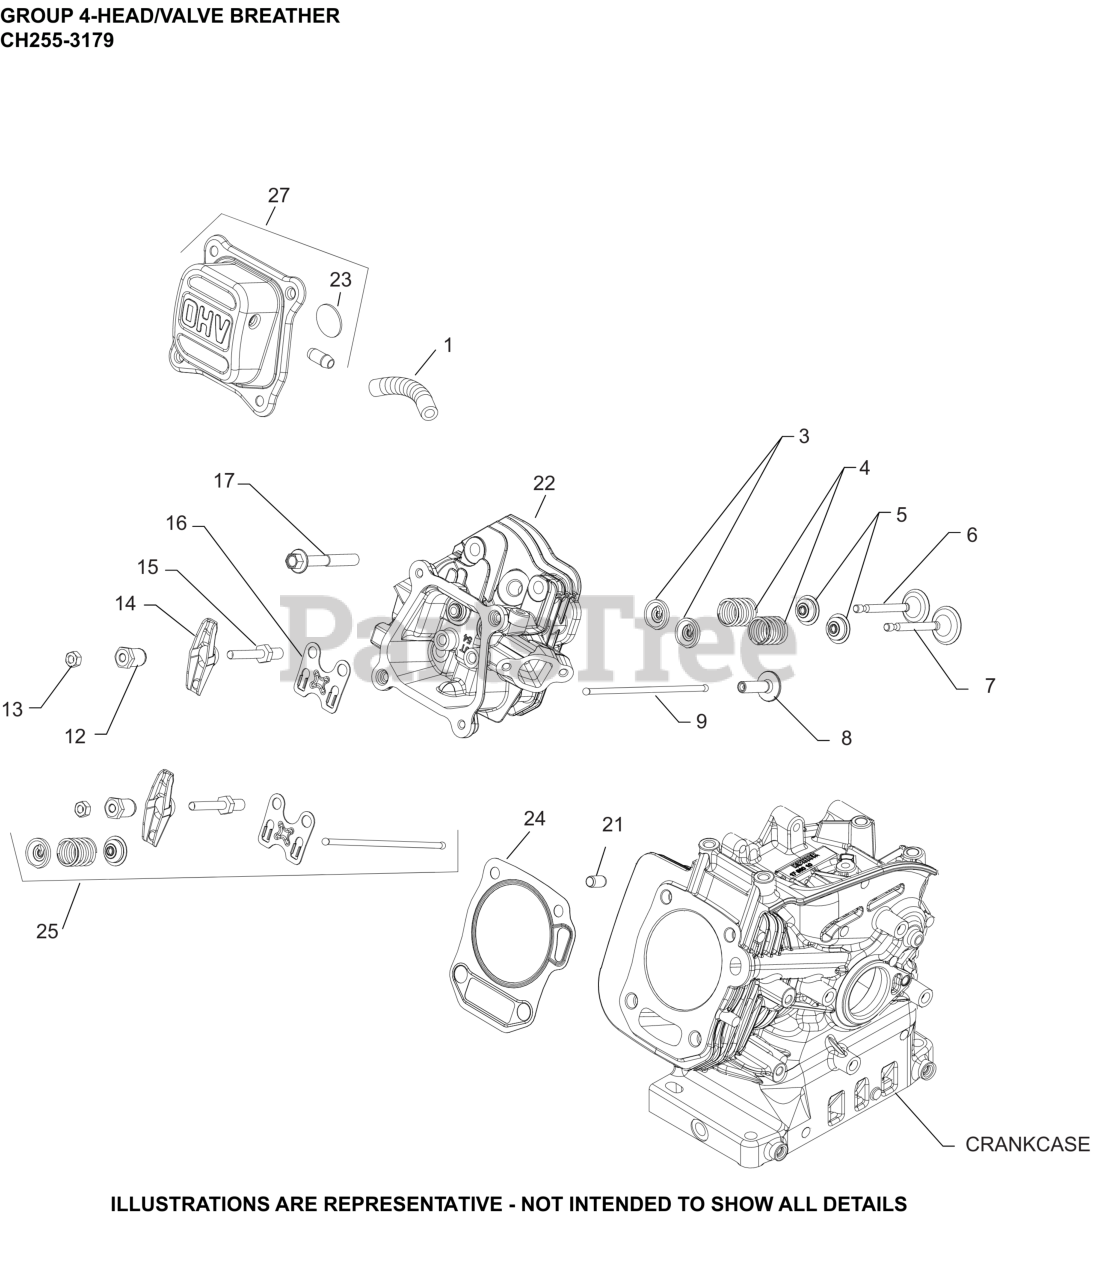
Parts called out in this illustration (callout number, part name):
1	TUBE, BREATHER
3	RETAINER, VALVE SPRING
4	SPRING, VALVE
5	SEAL, VALVE
6	VALVE, EXHAUST
7	VALVE, INTAKE
9	ROD, PUSH-(#1841101S)
12	PIVOT, ROCKER ARM
13	NUT, HEX JAM
14	ARM, ROCKER
15	STUD, ROCKER ARM-USE 14 072 22-S
16	PLATE, PUSHROD GUIDE
17	SCREW, HEX FLANGE CYL HEAD
21	PIN, DOWEL (8mm)
21	DOWEL, CYLINDER HEAD
22	CYLINDER HEAD
23	REED, BREATHER
24	GASKET, CYLINDER HEAD
25	KIT, VALVE TRAIN
27	COVER, VALVE ASSEMBLY
